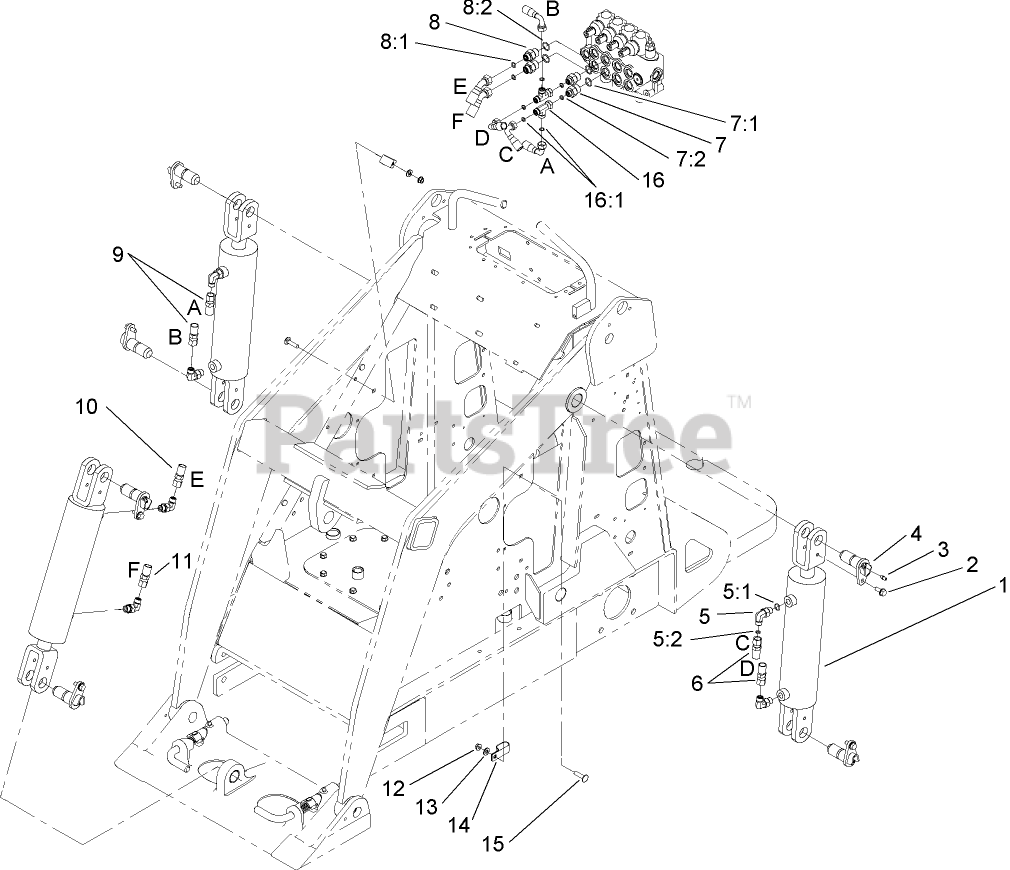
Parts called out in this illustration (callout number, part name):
1	HYD CYLINDER ASM
2	BOLT-SHOULDER
3	FITTING-GREASE
4	PIN-PIVOT
5	FITTING-ELBOW 90
5:1	O-RING
5:2	O-RING
6	HYD HOSE ASM
7	FITTING-STR
7:1	O-RING
7:2	O-RING
8	FITTING-STRAIGHT
8:1	O-RING
8:2	O-RING
9	HOSE-HYD
10	HOSE-HYD
11	HOSE-HYD
12	NUT-LOCK, NI
13	WASHER-PLAIN
14	CLAMP-R, DOUBLE
15	SCREW-CARR
16	FITTING-HYD
16:1	O-Ring
